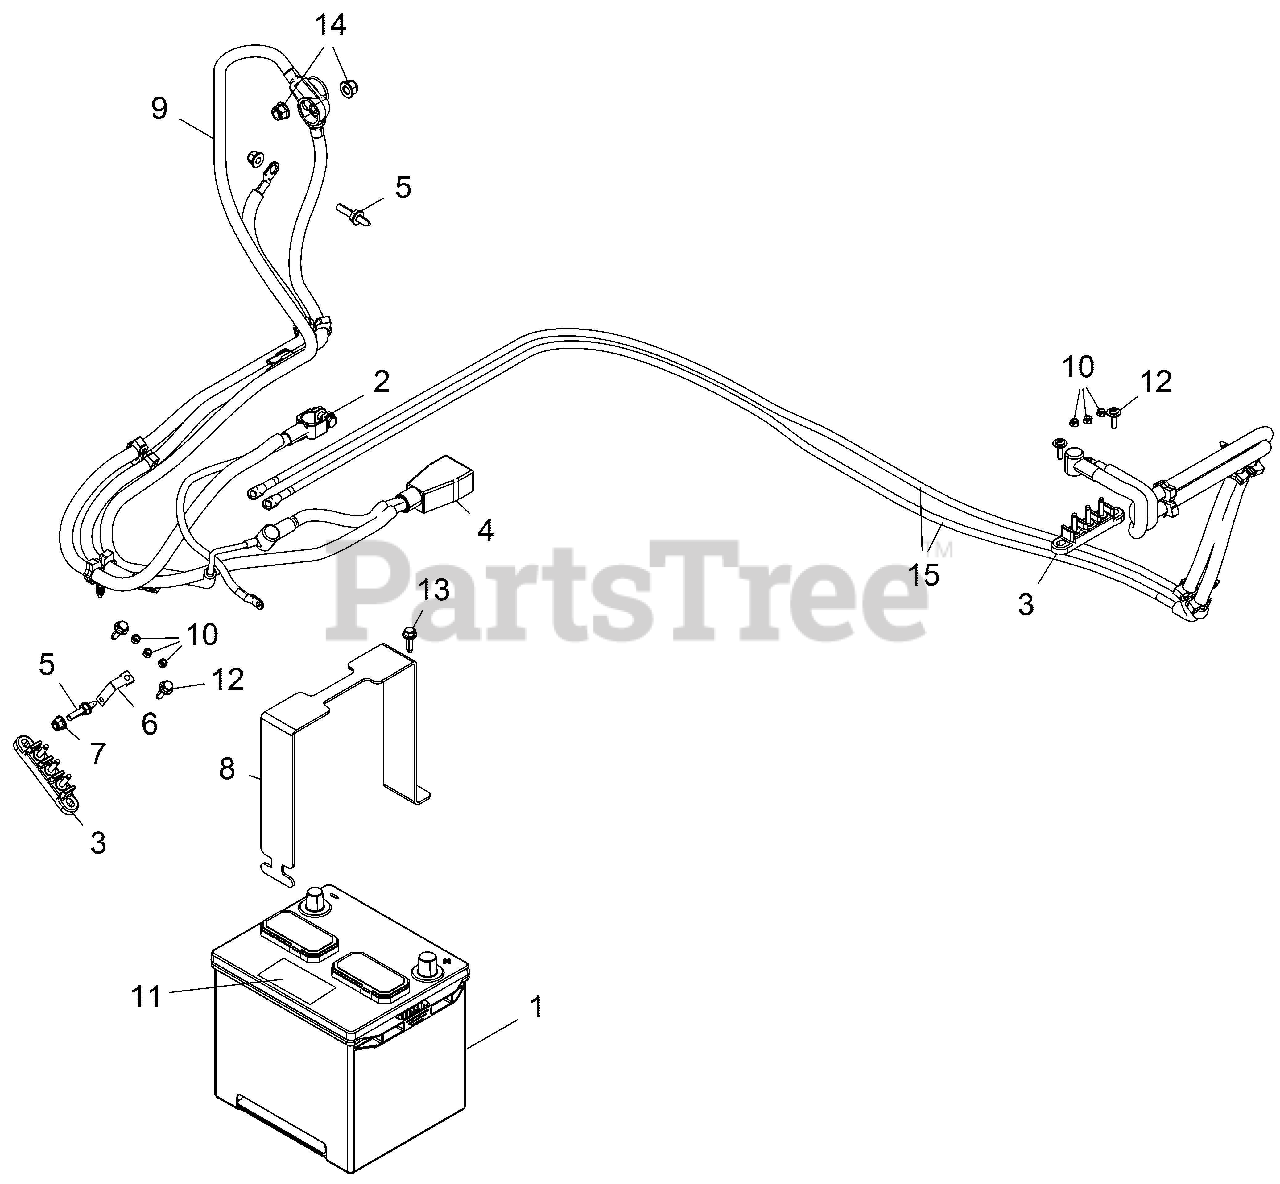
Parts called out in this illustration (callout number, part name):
1	#N/A
2	ASM.,CABLE, BAT TO GROUND/TERM
3	BLOCK, TERMINAL, 3 POST,TALL
4	CABLE, ALTERNATOR, BATTERY
5	STUD-M6X1.0X19-M6 TAPTITE
6	STRAP-GROUND
7	NUT-M6 FLANGE,NYLOK
8	BRKT-BATTERY STRAP GALV
9	CABLE, BATTERY TO ALT.
10	NUTS-10-32 KEPS
11	DECAL, BATTERY
12	SCR-10-24X3/4 PH/TX/TRI-SEMS Y
13	SCR-M6X1.0X20,HXHD,FLG,TDFM,BL
14	NUT-M8X1.25,HXFLG,NYLON INS
15	CABLE-TERMINAL BLOCK,GRND,ACC.
